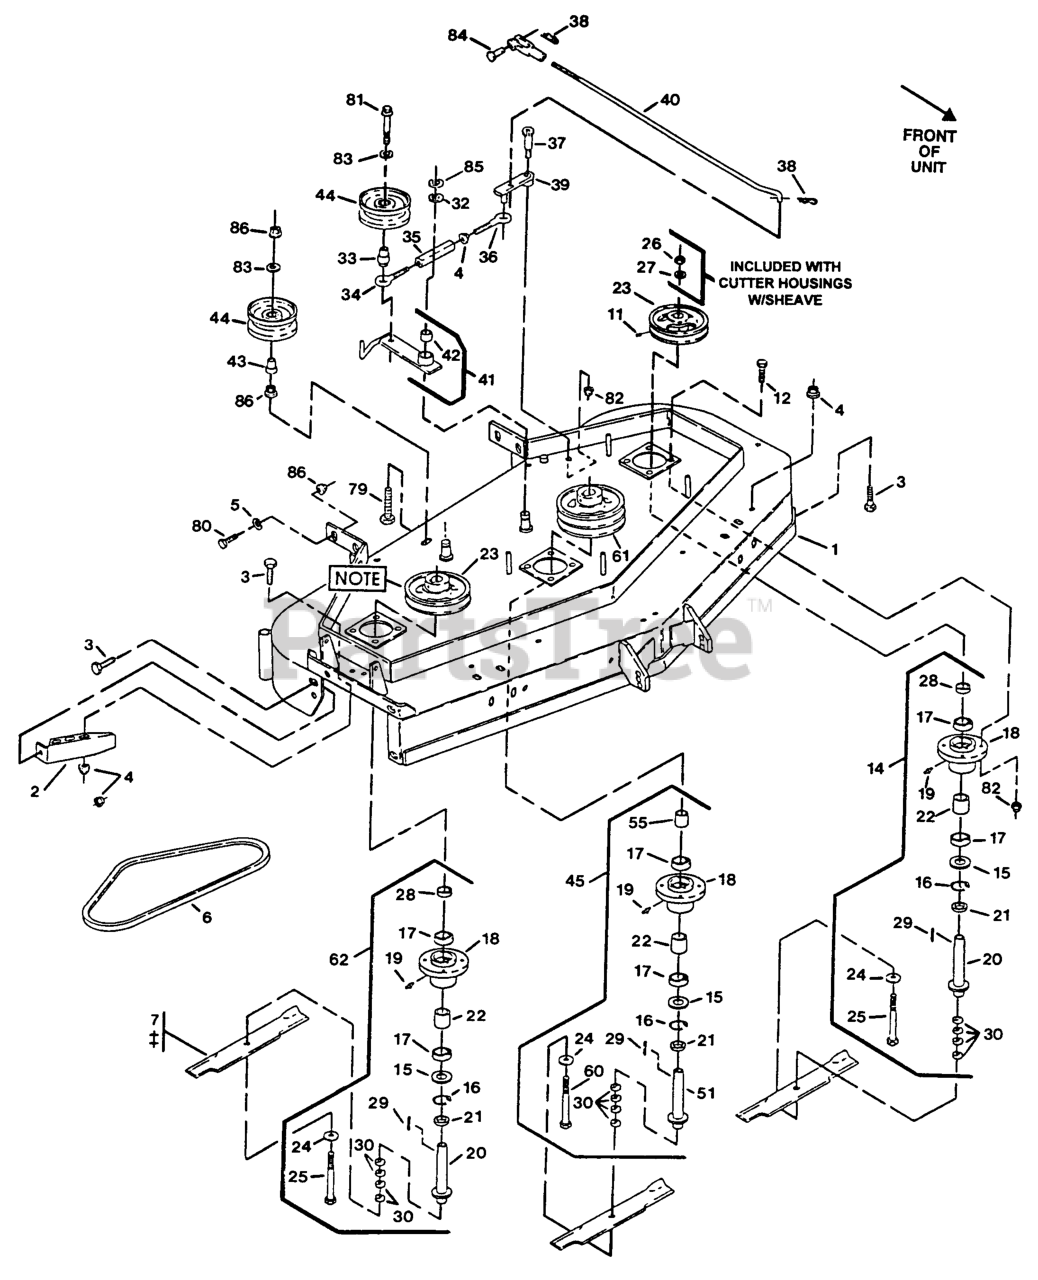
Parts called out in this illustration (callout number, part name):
2	WLD, DISCHARGE BAFFLE
11	SCREW-SET
14	ASM,HOUSING CUTTER
15	SEAL,DUST
16	RING,SNAP WLDS N5000-244
18	HOUSING,CUTTER
21	SPACER,BEARING &SPINDLE
22	SPACER,BRG/BRG
24	WASHER-SPRING
25	SCREW-CAP, HH
27	WASHER-RETAINER, SHEAVE
31	YOKE-ADJUSTABLE
32	WASHER-SPINDLE
33	BUSHING-ENGAGEMENT
34	EYEBOLT-THREAD, LH
35	BODY-TURNBUCKLE
36	EYEBOLT-THREAD, RH
37	BOLT,SHLDR KSKH
38	PIN-COTTER
42	BEARING,POWDERED METAL
55	SPACER,BEARING/SHEAVE
60	SCRW,CAP HH 5/8-18X8.5
79	BOLT,TAP HH3/8-16X2-1/4
84	PIN-CLEVIS
